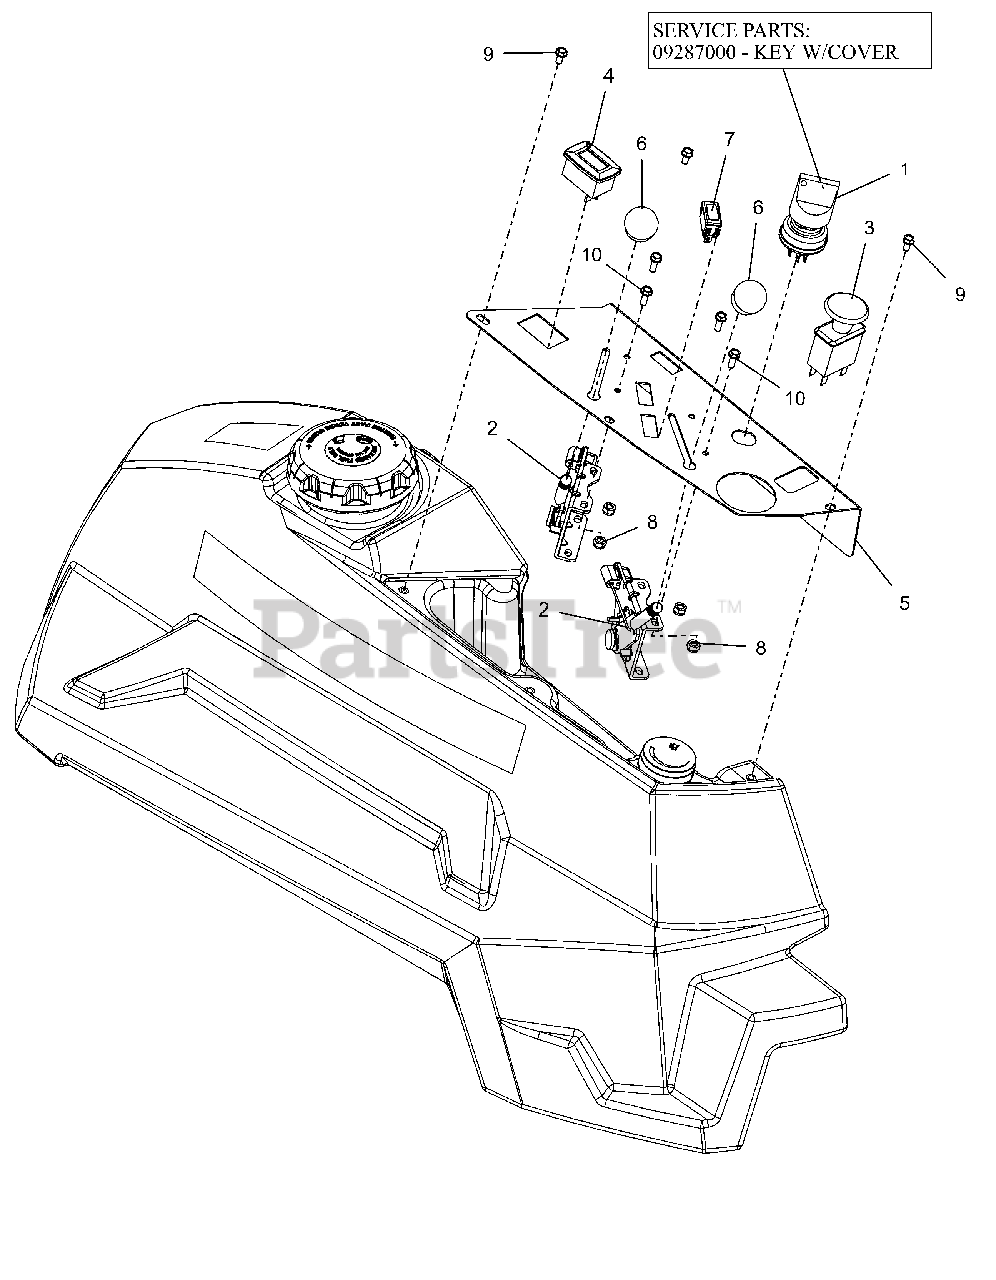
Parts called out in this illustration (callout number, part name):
1	SWITCH, IGNITION
1	KEY, W/ SHIELD
2	CABLE, PRO-CTRL 35.50"
3	SWITCH, CLUTCH
4	METER, HOUR W/MAINTENANCE
5	PT400 CONTROL PANEL - RED
6	KNOB-CONTROL-BLACK .38-16X.50
7	LIGHT,INDICATOR
8	@NUT-LK-NYL 10-24 W/INSRT YWZC
9	SCR-MCH 10-24X.38 HWHSTAINLESS
10	@SCR-MCH 10-24X.50 HWH YWZC
